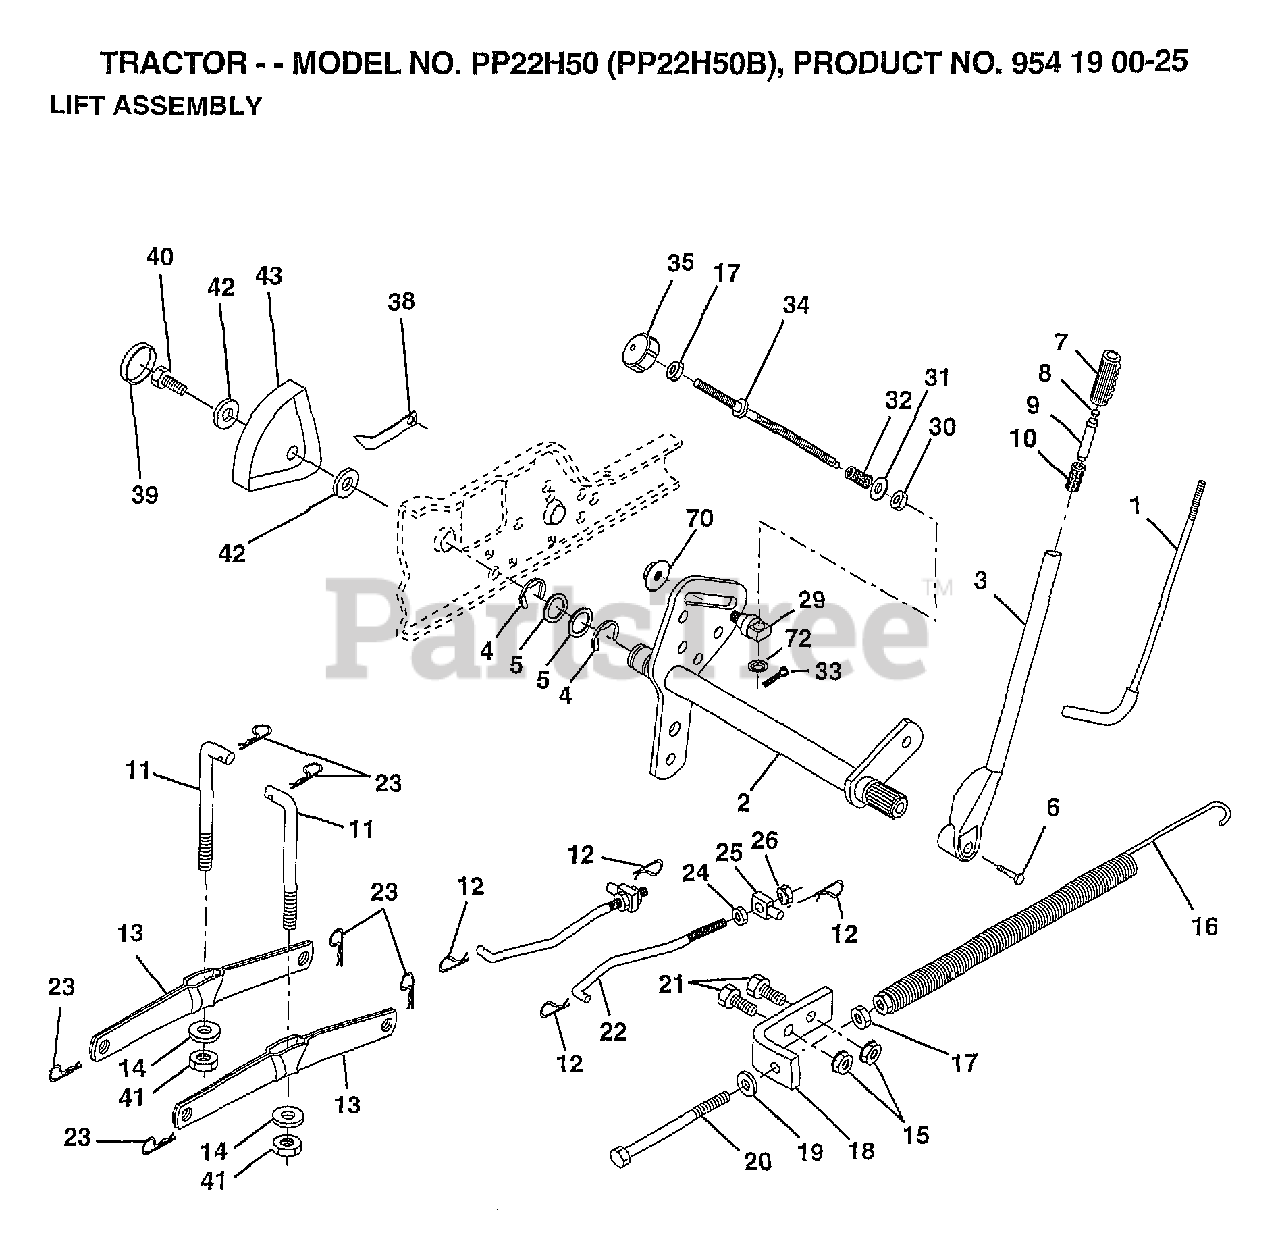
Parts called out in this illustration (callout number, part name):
1	LEVER ROD LT
2	SHAFT AMS LIFT
4	E-RING
5	WASHER
6	"BOLT,HEX"
7	GRIP
10	SPRING T
11	LINK.LIFT.MWR.VGT
12	RETAINER SPRING
13	ARM SUSP REAR
14	BEARING PVT LH
17	NUT
18	BRACKET SPRING AS
19	WASHER
20	BOLT-ADJ SPRING T
21	BOLT
22	LINK.FRONT
24	NUT
25	TRUNION
26	NUT.LK.W/WSH.1/2.
29	TRUNNION
30	NUT T
31	WASHER
32	SPRING.COMP.INF.H
34	ROD.ADJ.LIFT
35	KNOB INF 3/8-16
38	POINTER HEIGHT INDICATOR
39	"PLUG,HOLE"
40	SCREW
41	NUT.CROWNLOCK.3/8
42	WASHER
43	HEIGHT INDICATOR
70	NUT.HXFLG.LOCK.
72	NUT PUSH PHOS & OIL
